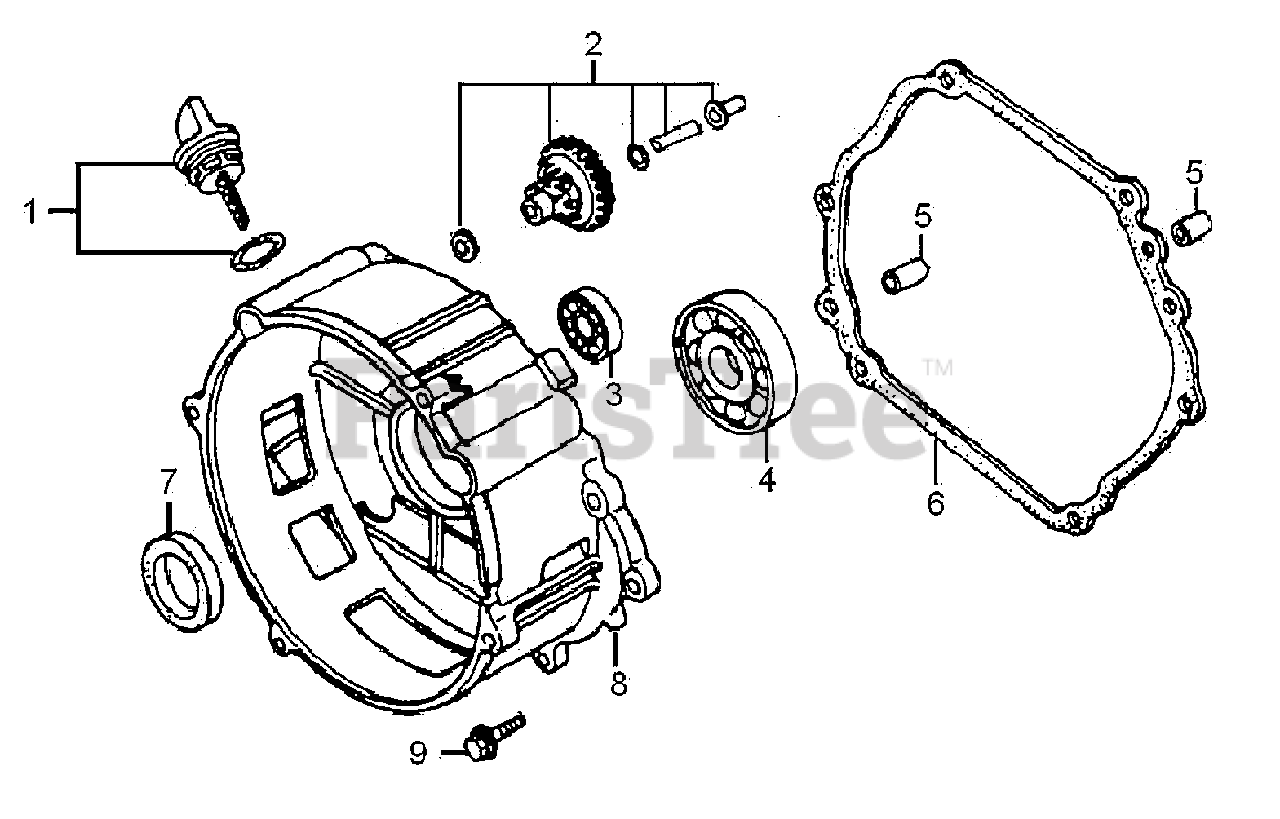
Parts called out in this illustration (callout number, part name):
1	CAP COMP., OIL FILLER
2	GOVERNOR ASSY.
3	BEARING, RADIAL BALL 6207
4	BEARING, RADIAL BALL 6202
5	PIN, DOWEL 8×12
6	PACKING, CASE COVER
7	OIL SEAL 35×52×7
8	CRANKCASE COVER
9	BOLT, FLANGE M8×40
